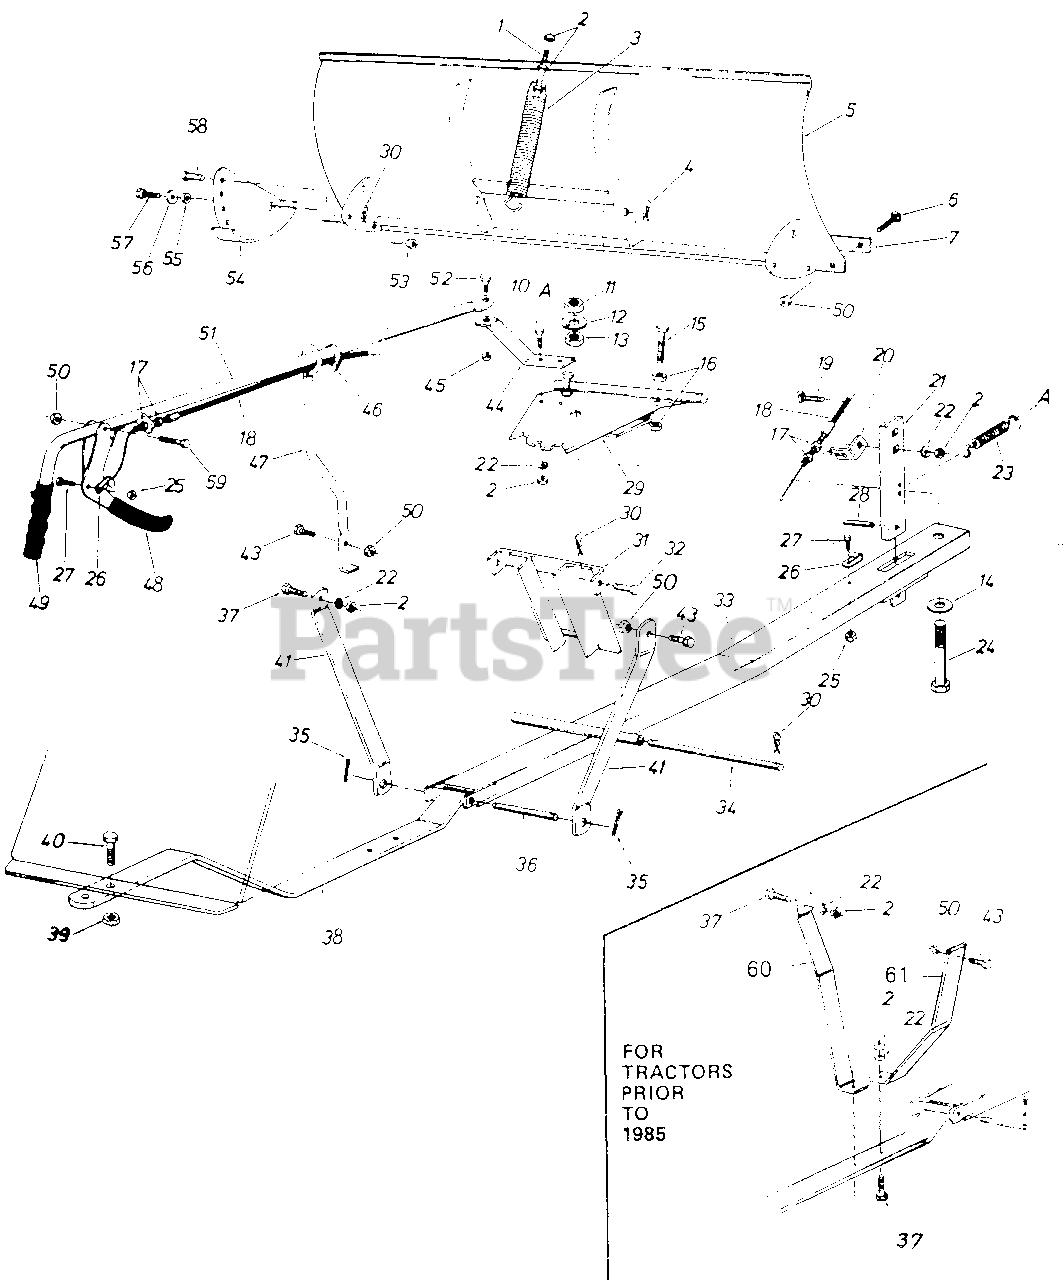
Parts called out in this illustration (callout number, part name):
1	Hex Scr. 3/8-16 x 4.50" Lg.
2	Hex Nut 3/8-16 Thd.
3	Blade Adjustment Spri ng
4	Hair Pin Cotter 5/32" Dia.
5	48" Blade Ass'y.
6	Carriage Bolt 5/16-18 x 75" Lg.*
7	Wear Plate 48"
10	Hex Scr. 3/8-16 x 1.00" Lg.*
11	Hex L.-Nut 3/4-10 0 Thd.
12	Fl.-Wash..810" I.D. x 2.00" O.D.
13	Hex Jam Nut 3/4-10 0 Thd.
14	Fl.-Wash..810" I.D. x2.00" O.D.
15	Hex Scr. 1/2-13 x 2.00" Lg.
16	Hex Nut 1/2-13 0 Thd.
17	Hex Jam Nut 5/16- 0 24 Thd.*
18	Control Cable Assly.
19	Carriage Bolt 3/8-16 0 x 1.25" Lg.*
20	Cable Guide Bracket
21	Angle-Lock Bar
22	L. Wash. 3/8" Scr.*
23	Angle Lock Spring
24	Hex Scr. 3/4-10 x 4.00" Ly.
25	Hex L.-Nut 1/4-20 Thd.
26	Clevis Lanyard Fitting
27	Hex Scr. 1/4-20 x .75" Lg.*
28	Spring Pin Spirol 1/4" Dia. x 1.00" Lg.
29	Pivot Plate Ass'y.
30	Hair Pin Cotter 3/32" Dia.
31	Guide Bracket Ass'y.
32	Clevis Pin 1/2" Dia. x 1.00" Lg.
33	Push Bar Ass'y.
35	Cotter Pin 5/32" Dia. x 1.00" Lg.*
37	Hex Scr. 3/8-16 x 1.25" Lg.*
38	Hanger Bracket Ass'y.
39	Hex L.-Nut 5/8-11 0 Thd.
40	Hex Scr. 5/8-11 x 1.50" Lg.
41	Hanger Link
43	Hex 5/16-18 x 1.00" Lg. *
44	BIade Pivot B racket
45	Hex Jam Nut 3/8-16 Thd.
46	Nylon Cable Tie
47	Tube Guide Ass' y.
48	Clutch Grip Ass'y.
49	Grip-3/4" Handle
50	Hex L-Nut 5/16-18 Thd.
51	Tube Handle Ass'y.
52	Shld. Scr.-Special 3/8-16 Thd.
53	Hex L.-Nut 3/8-16 0 Thd.
54	Skid Assembly
55	Spacer
56	Fl.-Wash..385" I.D. x 1.00" O.D.
57	HexScr. 3/8-16 x .75" Lg.*
58	ClevisPin5/16" Dia. x.75" Lg.
59	Hex Scr. 5/16-18 x 1.50' Lg.
60	Mounting Brkt.-L.H.
61	Mounting Brkt.-R.H.
